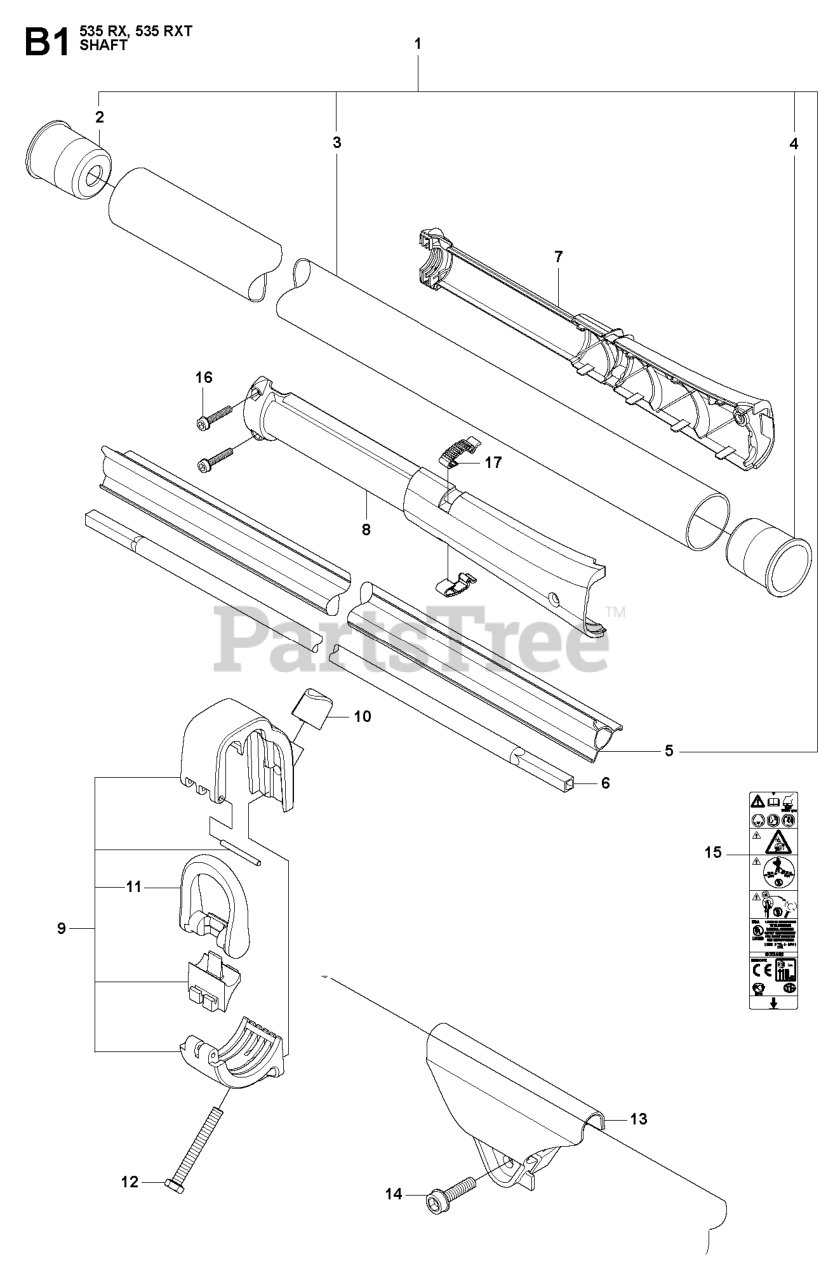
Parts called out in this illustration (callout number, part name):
1	TUBE
2	PLUG
3	TUBE
5	GUIDE
6	SHAFT
7	WEAR PROTECTION RIGHT
8	WEAR PROTECTION LEFT CPL
9	SUPPORT LOOP
9	LOOP ASSY
12	SCREW M6S 5X20
12	SCREW M6S 5X40
13	CABLE HOLDER
15	LABEL WARNING TRIMMERS AND BRU
